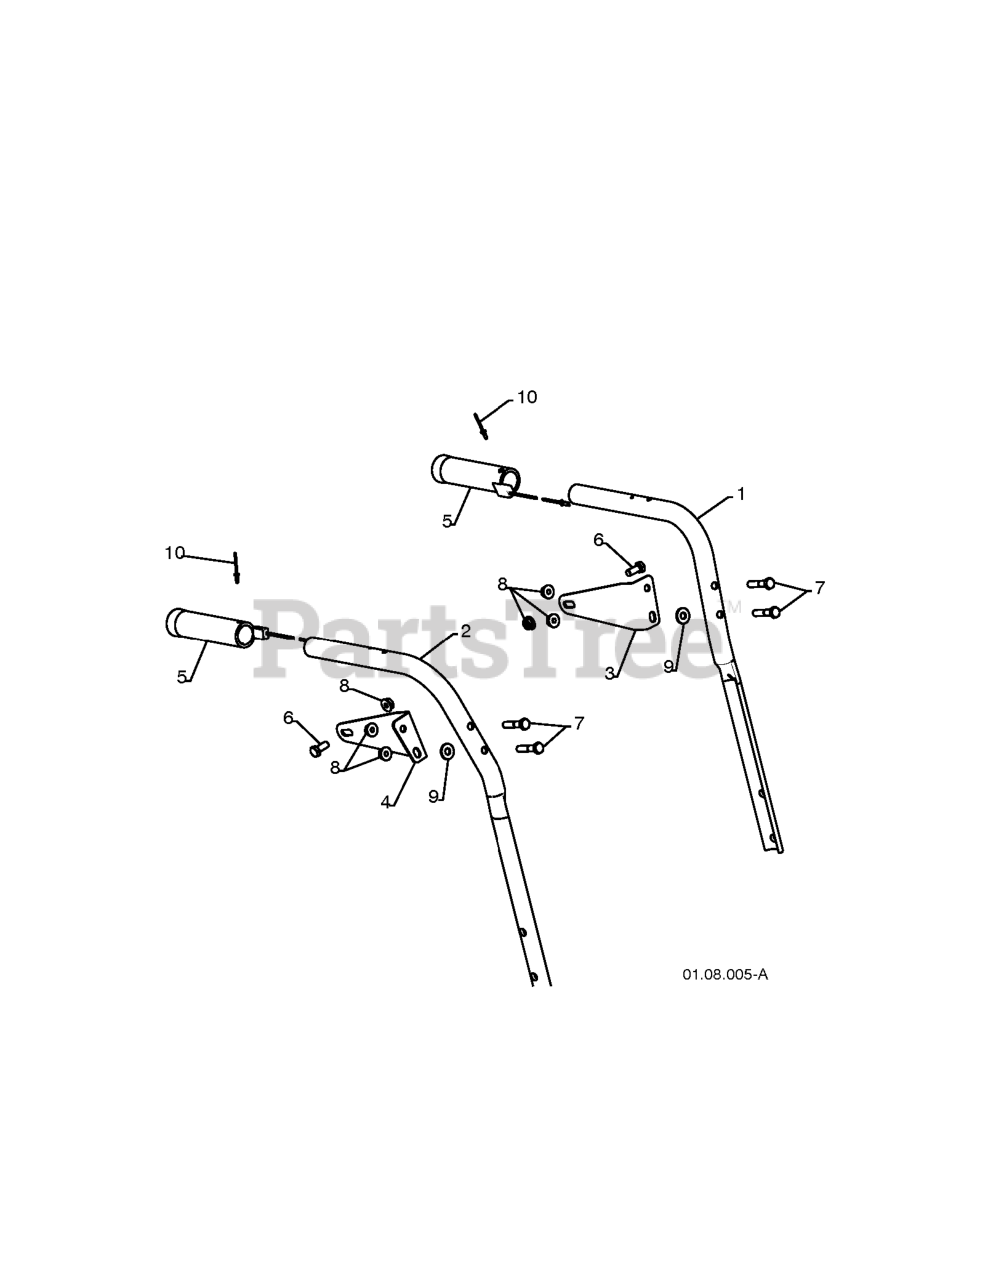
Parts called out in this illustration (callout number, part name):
1	TUBE.HANDLE.PLOW.LH.GREY
2	TUBE.HANDLE.PLOW.RH.GREY
3	BRACKET.PANEL.LH.
4	BRACKET.PANEL.RH
5	GRIP.HANDLE.HEATED
6	BOLT.FIN.HEX.5/16-18X3/4
7	HEX BOLT
8	NUT.LOCK.5/16-18
9	WASHER.20X8.5
10	RIVET.POP.1/8X
